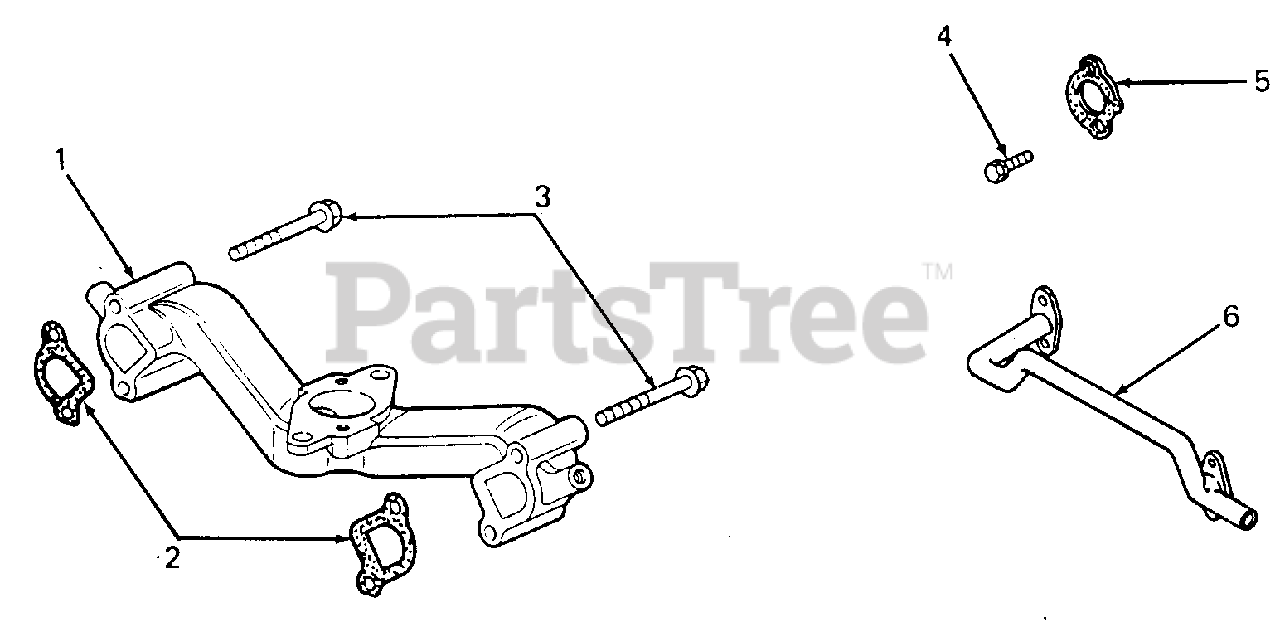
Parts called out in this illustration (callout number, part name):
1	Manifold Assy
2	Gasket, Intake Manifold
3	Screw, Sems
4	Screw, Sems
5	Gasket, Exhaust Manifold
